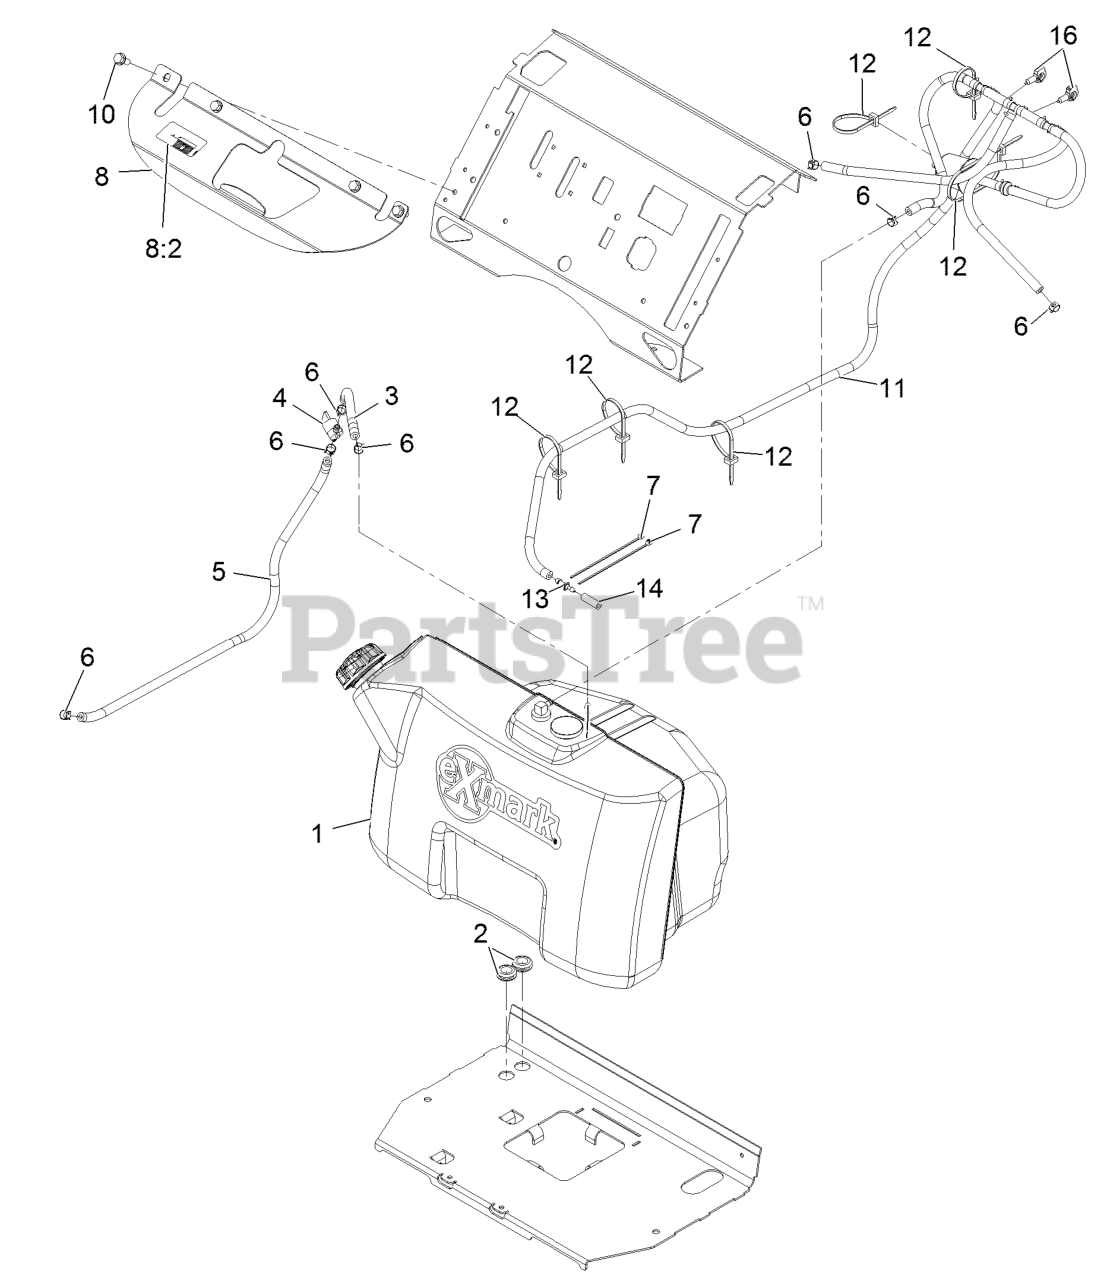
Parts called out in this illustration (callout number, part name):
2	GROMMET
3	HOSE-FUEL
4	VALVE-FUEL
5	HOSE-FUEL
6	CLAMP-HOSE
7	TIE-CABLE
8	BRACKET-TANK
8:2	DECAL-FILL, FUEL
10	SCREW-THD ROLL, HWH
11	VENT ASM
12	TIE-CABLE
13	FITTING-STRAIGHT
14	HOSE-FUEL
16	CLIP-HARNESS
